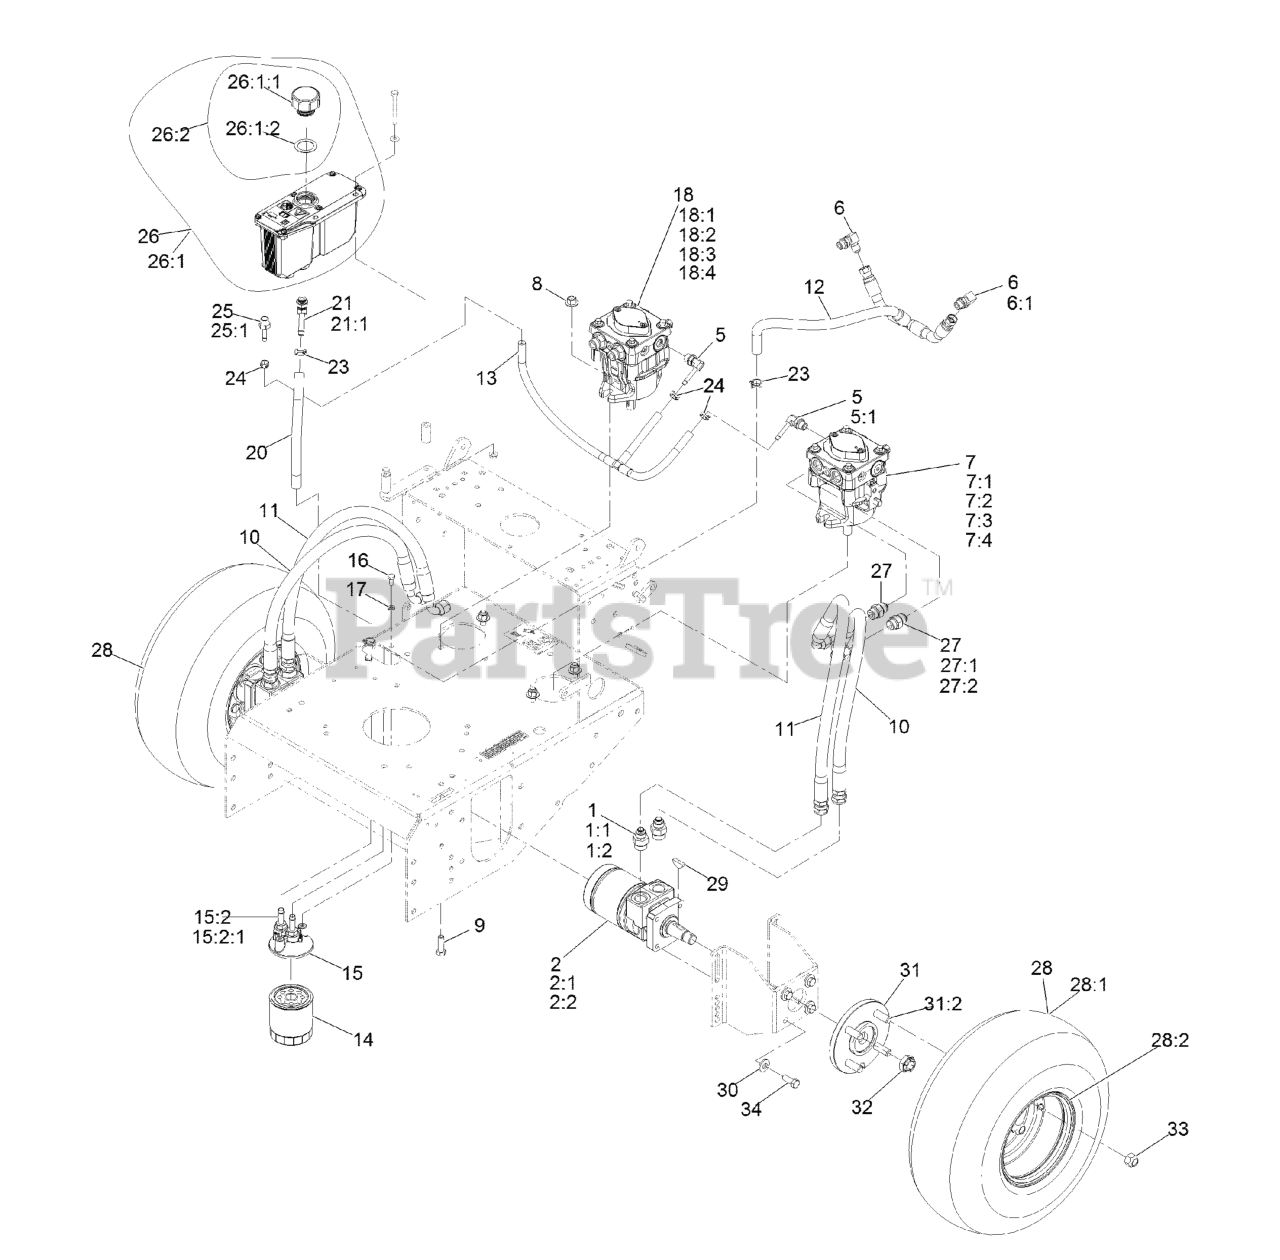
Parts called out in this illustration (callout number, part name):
1	FITTING-STRAIGHT
1:1	O-RING
2	HYD MOTOR ASM
2:1	SEAL KIT
2:2	BEARING AND SEAL KIT
5	ELBOW-90 DEG
5:1	O-RING
6	FITTING-ELBOW, 90 DEG
6:1	O-RING
7	LH HYD PUMP ASM
7:1	INPUT SHAFT KIT
7:2	BEARING-THRUST
7:3	CYLINDER BLOCK KIT
7:4	SEAL OVERHAUL KIT
8	NUT-FLANGE
9	SCREW-HH
10	HYD HOSE ASM
11	HYD HOSE ASM
12	CHARGE HOSE ASM
13	CASE DRAIN HOSE ASM
14	ELEMENT-FILTER, WINTER
14	FILTER-25 MICRON, BI-DIRECTIONAL
15	FILTER HEAD ASM
15:2	ADAPTER-STRAIGHT
15:2:1	O-RING
16	SCREW-HH
17	WASHER-LOCK
18	RH HYD PUMP ASM
18:1	INPUT SHAFT KIT
18:2	BEARING-THRUST
18:3	CYLINDER BLOCK KIT
18:4	SEAL OVERHAUL KIT
20	HOSE-CHARGE
21	FITTING-BARBED, 45 DEG
21:1	O-RING
23	CLAMP-HOSE
24	CLAMP-HOSE
25	ADAPTER-STRAIGHT
25:1	O-RING
26:1	Reservoir-HYD
26:1:1	Cap-Reservoir, HYD
26:1:2	GASKET-CAP
26:2	DECAL-WARNING
27	FITTING-STRAIGHT
28	WHEEL AND TIRE ASM
28:1	TIRE-TURFMASTER
28:2	RIM-WHEEL
29	KEY-WOODRUFF
30	WASHER-BELLEVILLE
31	WHEEL HUB ASM
31:2	STUD-WHEEL
32	NUT-LOCK
33	NUT-LUG
34	SCREW-HH
